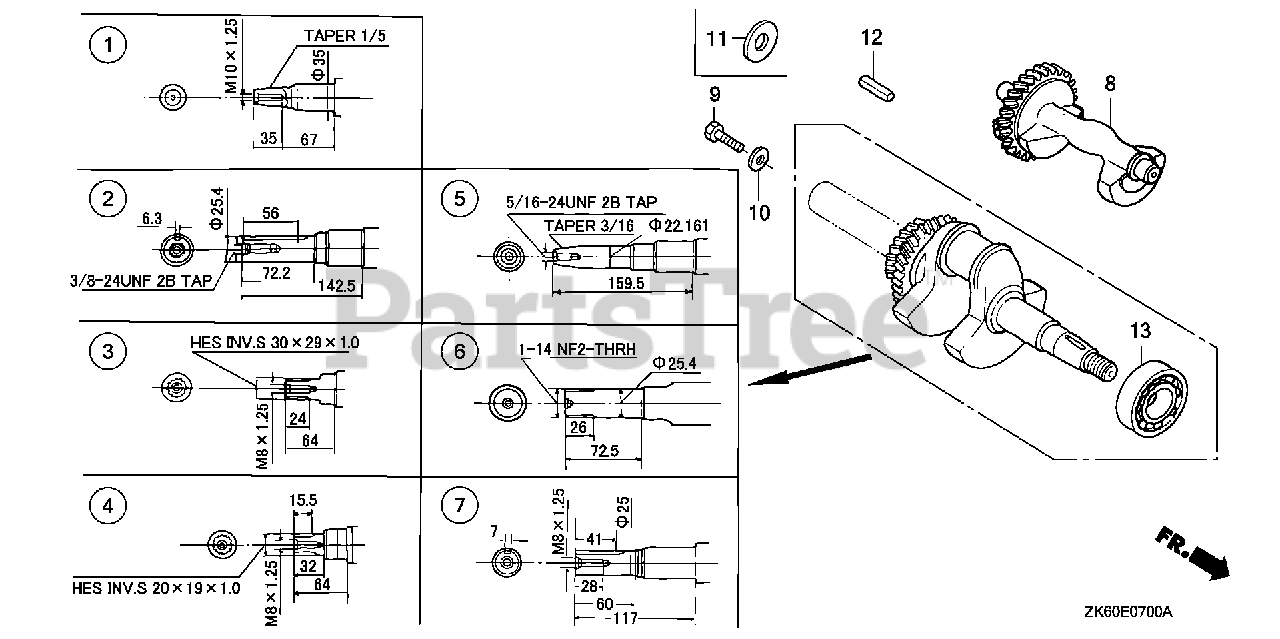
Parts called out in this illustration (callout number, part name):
5	CRANKSHAFT
8	WEIGHT, BALANCER
13	BEARING, RADIAL BALL (6207SH)
